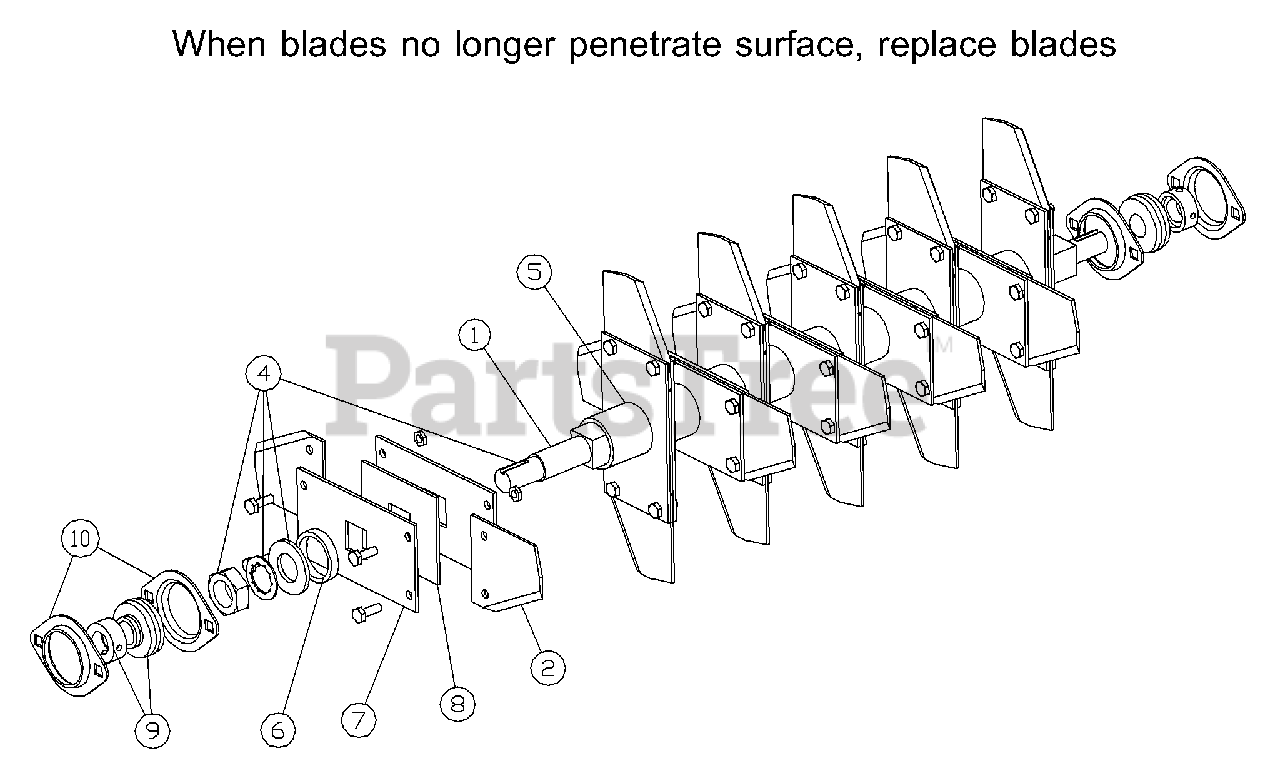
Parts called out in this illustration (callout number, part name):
1	Delta reel assembly
2	Blade set, Delta
4	Shaft, delta reel
5	Spacer, carrier, steel tube
6	End ring, steel
7	Plate, blade carrier
8	Plate, blade spacer
9	Bearing, 3/4 with locking collar
10	Stamping kit
